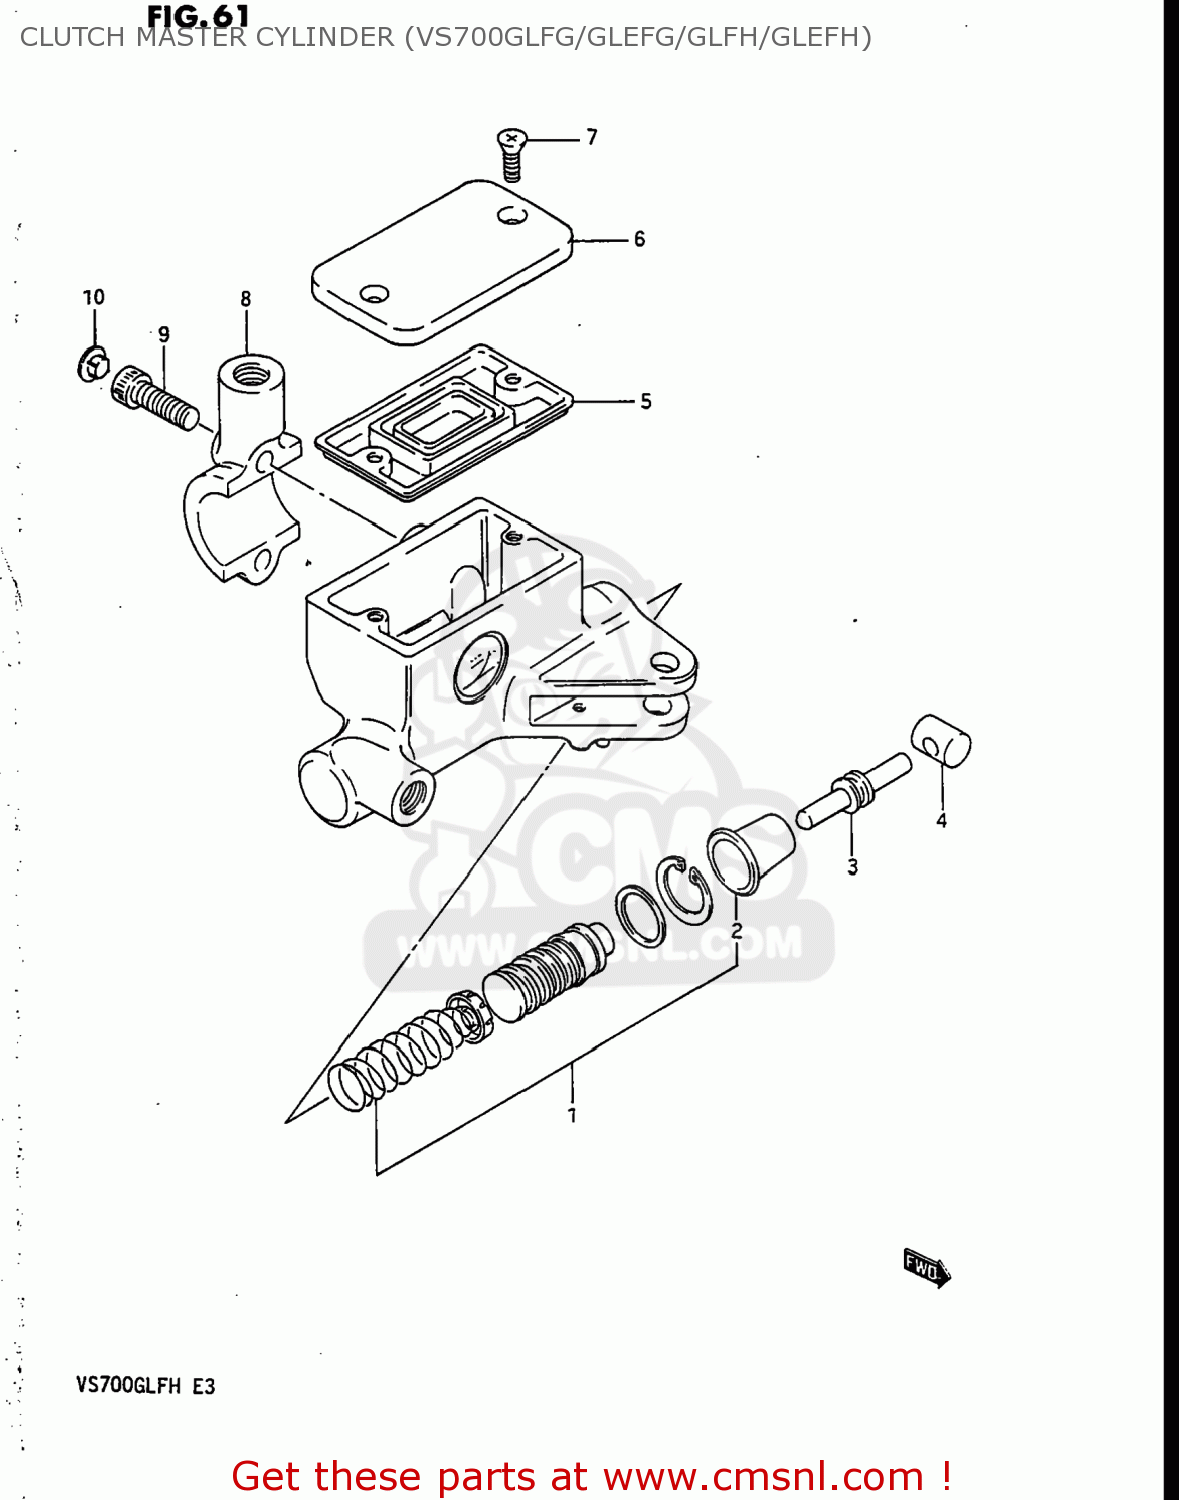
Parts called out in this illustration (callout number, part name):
1	PISTON & CUP SET
2	BOOT
3	PUSH ROD
4	BUSH
5	6
6	CAP
7	SCREW,RESERVOIR CAP
8	HOLDER
9	BOLT ,6X20
10	CAP(OD:10)
